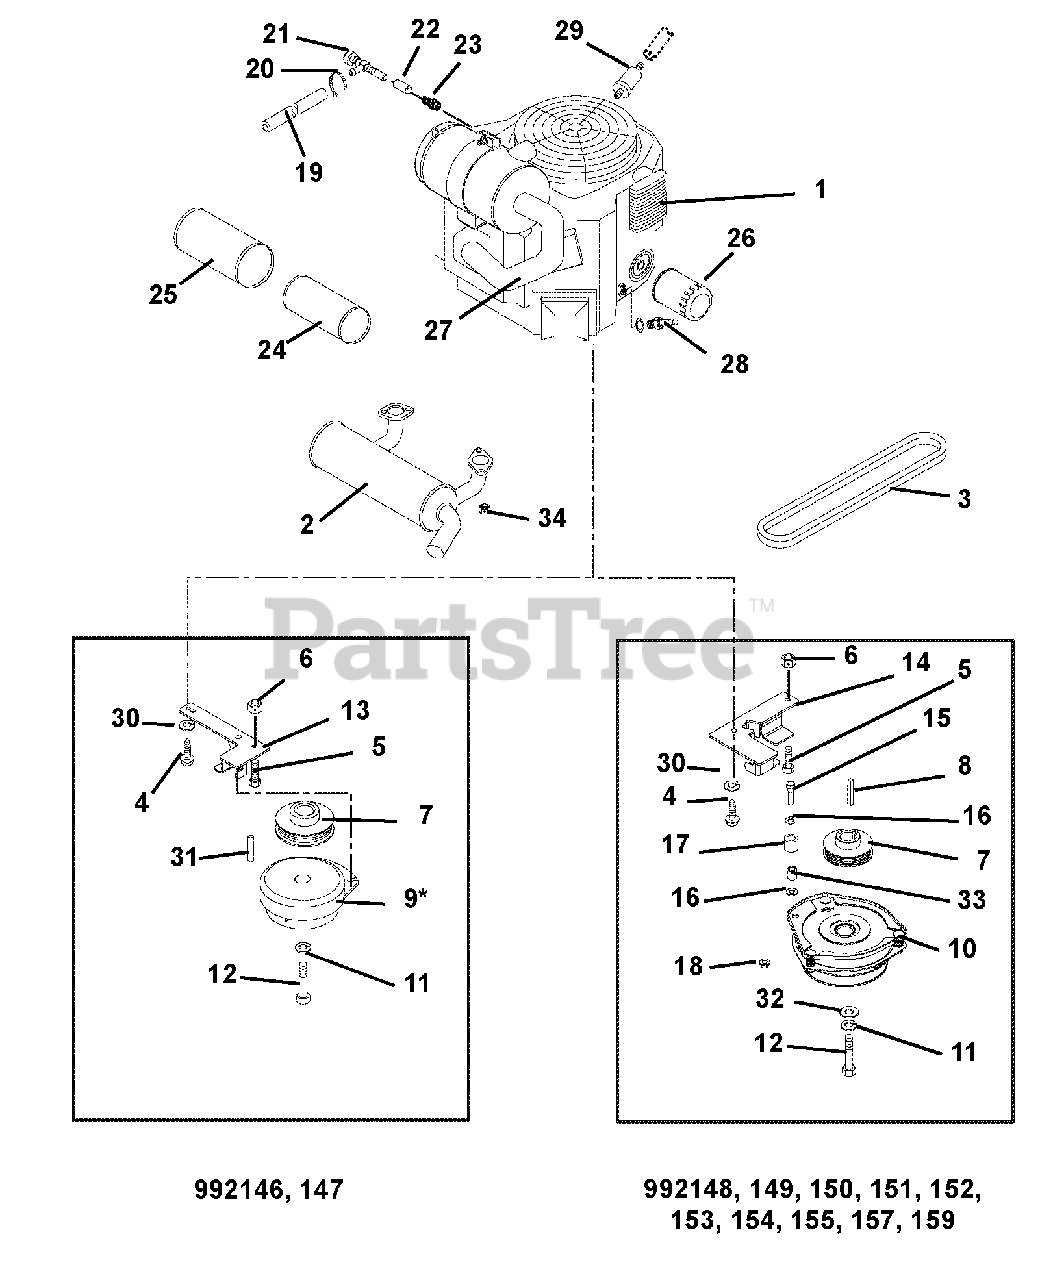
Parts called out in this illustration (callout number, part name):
1	Engine, 25hp Kawasaki (FH721V) (992148, 149, 151, 153)
2	Muffler, Kawasaki (992148, 149, 151, 153)
3	Belt, Poly-V
4	Screw, Tapping Hex Washer Head .38-16 x 1.50 (992146, 147, 148, 149, 150, 151, 153, 154, 155)
5	Bolt, Hex .31-18 x 1.75 Grade 5 (992146, 147, 148, 149, 150, 151, 153, 154, 155)
6	Nut, Locking Top Flange .31-18
7	Sheave, Poly V 1.127 x 3.275
8	Key-Square .25 x 3.50 x .25 SAE (992148, 149, 150, 151, 152, 153, 154, 155, 157, 159)
9	Clutch, Electric (992146, 147)
10	Clutch, Electric (992148, 149, 150, 151, 152, 153, 154, 155, 157, 159)
11	Washer, Locking .44 x .109
12	Bolt, Hex .44-20 x 3.00 Grade 5 YZ EP80
13	Anchor, Clutch (992146, 147)
14	Anchor Clutch (992148, 149, 150, 151, 152, 153, 154, 155, 157, 159)
15	Bolt-Hex .38-16 x 1.50 Grade 5 (992148, 149, 150, 151, 152, 153, 154, 155, 157, 159)
16	Washer-Flat-Steel .406 x .812 x .065 (992148, 149, 150, 151, 152, 153, 154, 155, 157, 159)
17	Bumper, Rubber .62 x 1.0 x .88 LG (992148, 149, 150, 151, 152, 153, 154, 155, 157, 159)
18	Nut-Locking-Top-Flange .38-16 (992148, 149, 150, 151, 152, 153, 154, 155, 157, 159)
19	Gas Line, Bulk .25 I.D. (992148, 149, 151, 152, 153, 157, 159)
20	Cable Tie LG 5-1/2 (992148, 149, 151, 152, 153, 157, 159)
21	Drain, 1/2" Drain
22	Adapter, .38 NPTF (992146, 147, 150, 154, 155)
23	Nipple, Pipe .375-18 NPTF x 3.00 (992146, 147, 150, 154, 155)
24	Element, Inner Safety (992148, 149, 150, 151, 152, 153, 154, 155, 157, 159)
25	Element, Outer Primary (992148, 149, 150, 151, 152, 153, 154, 155, 157, 159)
26	Oil Filter (992148, 149, 151, 153)
27	Hose, Air Intake (992150, 154)
28	Spark Plug (992148, 149, 151, 153)
29	Fuel Filter (992148, 149, 151, 153)
30	Washer, Lock .31 x .078
31	Key, Square .25 x 1 x 0.25 (992146, 147)
32	Washer, Flat Steel .469 x 2 x .25 (992148, 149, 150, 151, 152, 153, 154, 155, 157, 159)
33	Bushing, .407 x .625 x .813 (992148, 149, 150, 151, 152, 153, 154, 155, 157, 159)
34	Nut, Locking, Top M8-1.25
